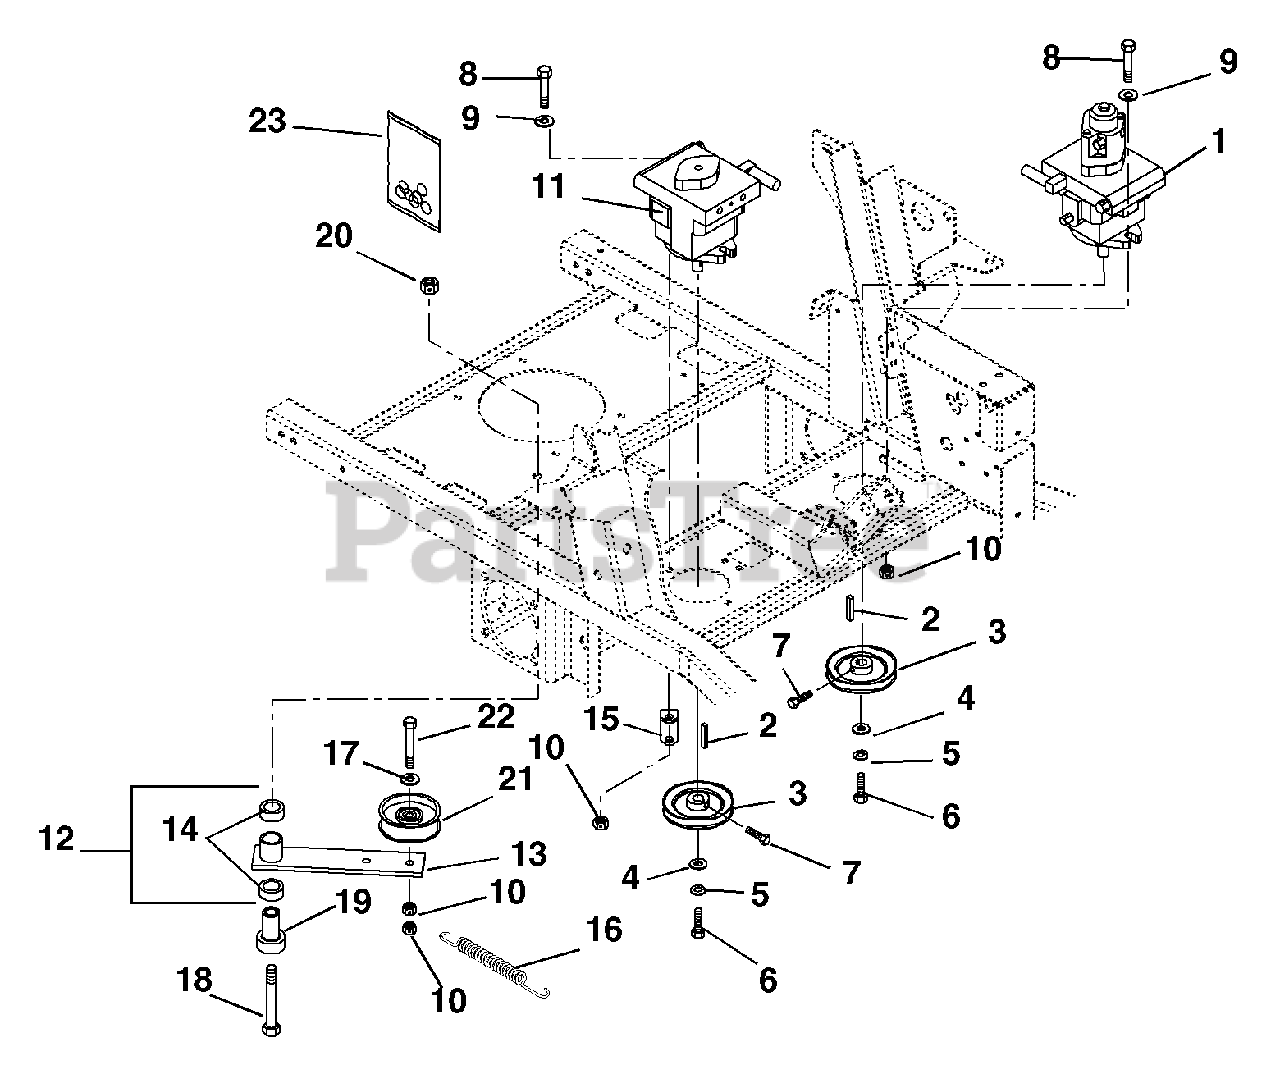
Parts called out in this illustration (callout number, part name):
1	HYDROSTAT, BDP-10A W/ AUX
2	KEY-STR 5MMX25MMX5MM
3	SHEAVE, PUMP .592 X 4.345
4	WSHR-FL-STL .281X1.0X.048 YWZC
5	@WSHR-LK .25X.062 REG YWZC
6	BLT-HEX M6 X 1.0X12 YWZC
7	@BLT-HEX .25-20X.50 GR5 YWZC
8	@BLT-HEX .38-16X1.25 GR5 YWZC
9	WSHR-FL-STL .390X.75X.125 YWZC
10	@NUT-LK-CTR .38-16 YWZC
11	HYDROSTAT, BDP-10A
12	ASSEMBLY,IDLER ARM GRD.DRIVE
13	WMT, IDLER ARM GROUND DRIVE
14	BRG, 1.00 X 1.12 X .75
15	ANCHOR, SPRING IDLER
16	SPRING, EXTENSION
17	WSHR-FL-STL .390X.75X.125 YWZC
18	@BLT-HEX .50-13X3.50 GR5 YWZC
19	BEARING, PEDESTAL
20	@NUT-LK-CTR .50-13 YWZC
21	IDLER, FLAT .377X4.0X.96W POLY
22	@BLT-HEX .38-16X2.25 GR5 YWZC
23	KIT, PUMP SEAL (P/N 2513018)
24	FAN, COOLING
